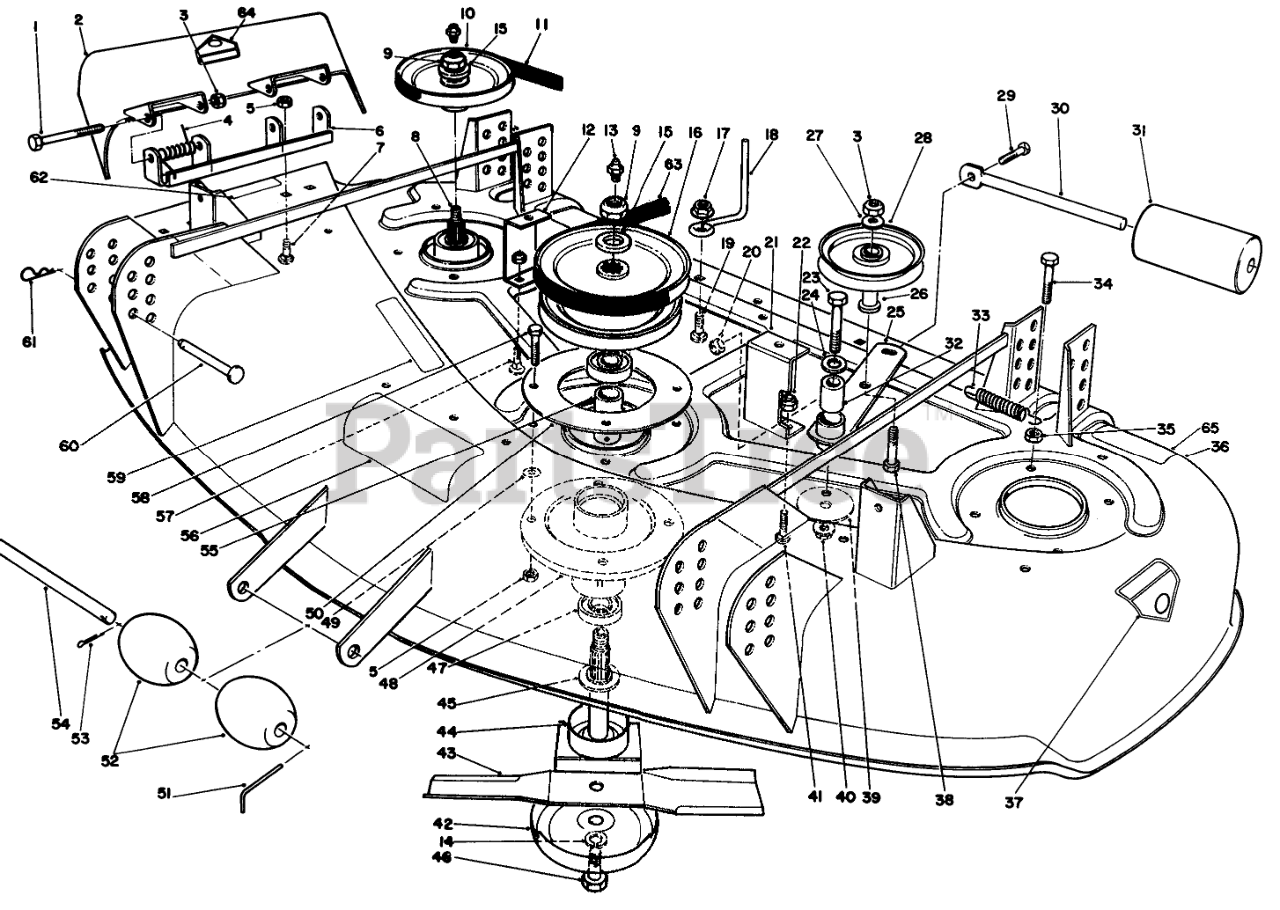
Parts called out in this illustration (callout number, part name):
1	SCREW-HH
2	Grass Deflector (Incl. Ref. #64)
3	NUT-HEX
4	SPRING
5	NUT-LOCK, CONE
6	PIVOT BRKT WA R/B
7	SCREW-CARR
8	SHAFT-SPINDLE
9	NUT-HEX
10	PULLEY-DECK
11	V-BELT
12	Bracket-Cover RH
13	FITTING-GREASE
14	WASHER-LOCK
15	WASHER
16	PULLEY-CENTER
17	NUT-HF
18	ROD-BELT
19	BOLT-CARR
20	NUT-LOCK, NI
21	Bracket-Cover
22	NUT-LOCK, NI
23	SCREW-HH
24	WASHER-FLAT
25	Idler Arm
26	BUSHING-PULLEY
27	WASHER-FLAT
28	PULLEY-IDLER
29	SCREW-HH
30	ROD-ROLLER
31	ROLLER-DECK
32	SLEEVE
33	Spring-Extension
34	SCREW-HH
35	NUT-JAM
36	Housing (Incl. Ref. #37, 56, 59, 62, 64, & 65)
37	DECAL-DANGER
38	SCREW-HH
39	WASHER-END
40	NUT-HF
41	SCREW-CARR
42	CUP-SCALP, ANTI
43	Blade
44	SHAFT-SPINDLE
45	SPACER-SPINDLE
46	SCREW-BLADE
47	BEARING-BALL
48	HOUSING-SPINDLE
49	WASHER-FLAT
50	DECK RING
51	PIN-SPECIAL
52	ROLLER
53	PIN-COTTER
54	SHAFT-ROLLER
55	SPACER-BEARING
56	DECAL-DANGER, THROWN OBJECT
57	BOLT-CARR
58	Screw
59	DECAL-DANGER
60	PIN-CLEVIS
61	PIN-HAIR
62	DECAL-DANGER
63	V-BELT, DRIVE
64	DECAL-DANGER
65	DECAL-TORQUE
